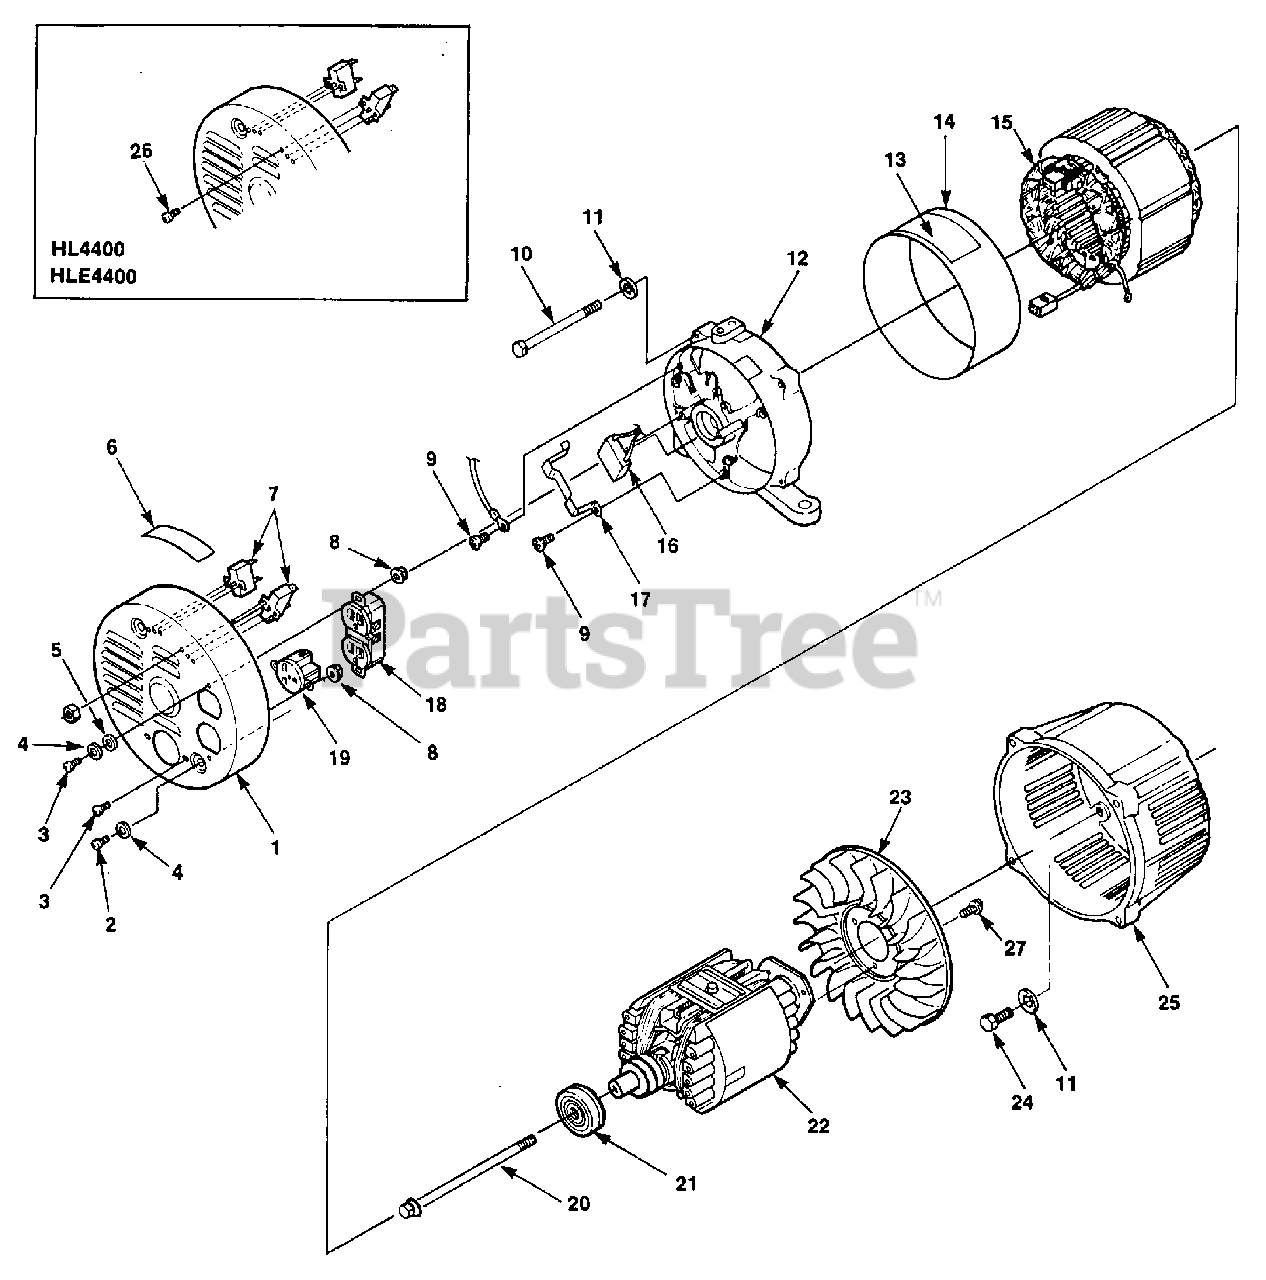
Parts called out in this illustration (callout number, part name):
1	END COVER
2	BOLT- End cover
3	SCREW- Rd. hd.
4	WASHER- Lock
5	WASHER- Flat
6	DECAL- Warning
7	BREAKER- Circuit (25 amp) w/nut
8	NUT- Hex
9	SCREW- (M5 x 12mm)
10	BOLT- Stator
11	WASHER- Lock
12	END- Bell
13	DECAL- Output
14	COVER- Stator
16	CAPACITOR
17	CAPACITOR HOLDER
18	RECEPTACLE (120v)
19	RECEPTACLE (240v)
20	BOLT- Rotor
21	BEARING- Ball
24	SCREW- Hex hd. (3/8-16 x 1 1/4")
27	SCREW- Hex tapping (M5 x 14mm)
